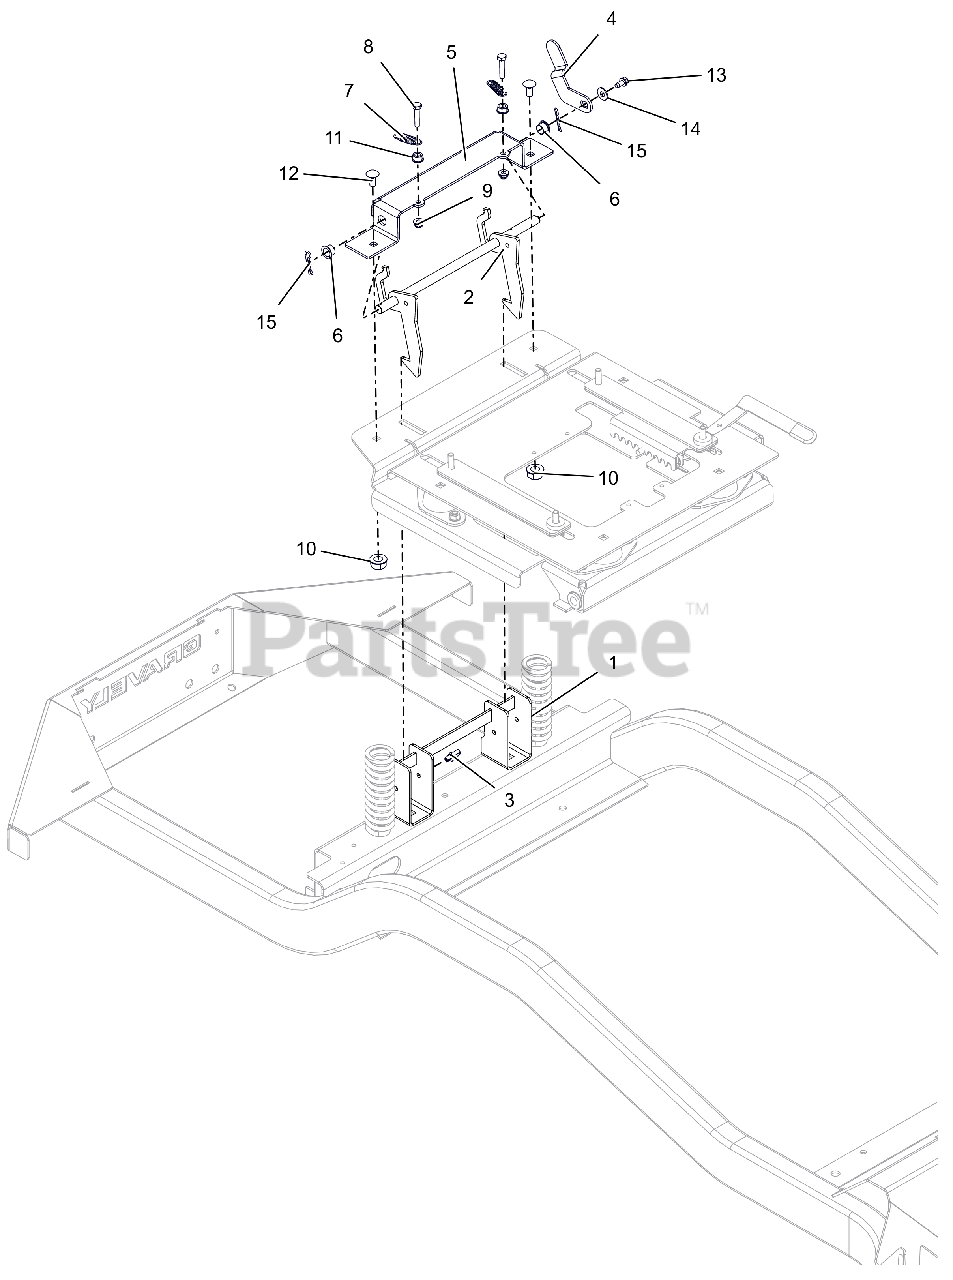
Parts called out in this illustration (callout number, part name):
1	WLDMT, LATCH RECEIVER
2	WLDMT, SEAT
3	ROUTING CLIP (1/2" ID)
4	LEVER, SEAT
5	BRKT, SEAT
6	BUSHING, POLYLINER-.50 SPLIT
7	SG-TENS .063X.44X1.56
8	BLT, HEX .25-20X1.25 G5 ZCC
9	NUT,NYL-FLG .25-20 GF ZCC
10	NUT-LK-CTR-FLG .500-13 GG ZCC
11	NUT,LK-CTR-FLG .31-18 GF ZCC
12	BLT,RHSN .31-18X.75 G5 ZCC
13	SCR-TAP .25-20X.50 HWH ZCC
14	WSHR, FLT .312X.734X.065 ZCC
15	PIN-HAIR INT .08X.38X1.42 YWZC
